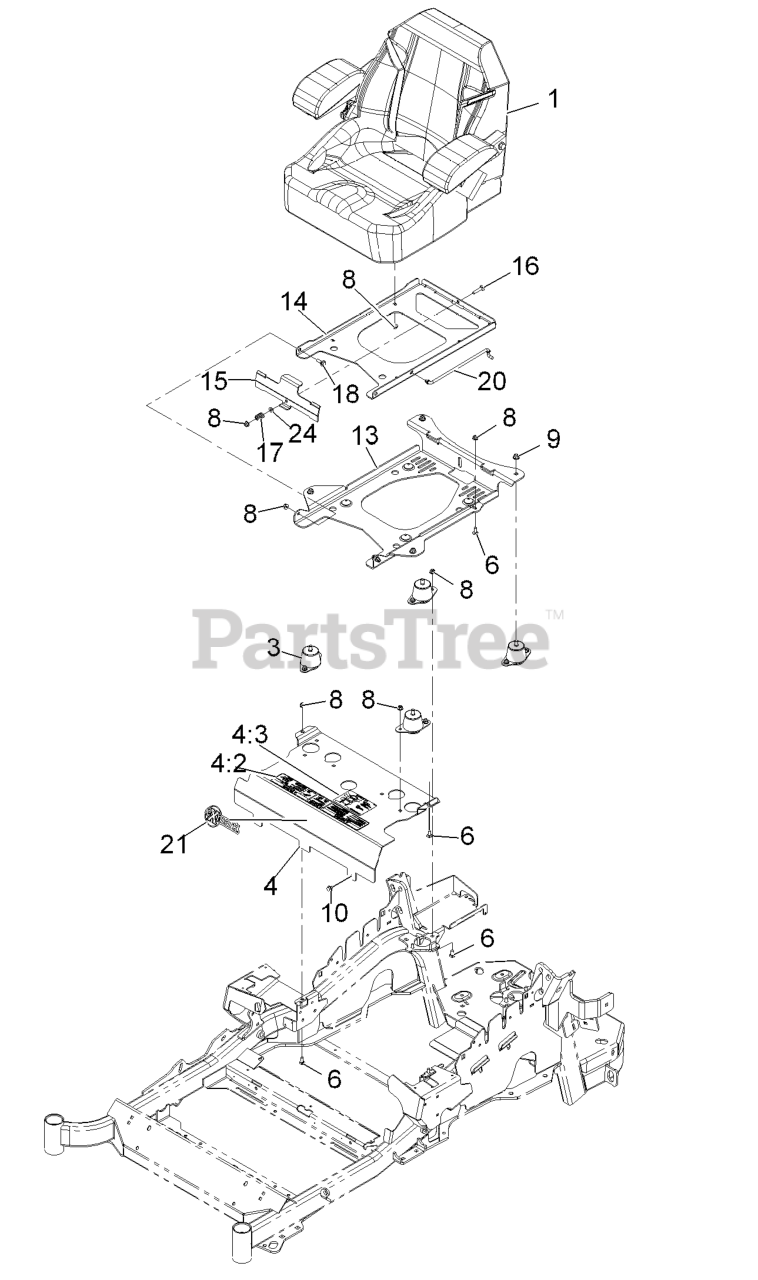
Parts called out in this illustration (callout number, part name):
3	ISOLATOR-SEAT
4	MOUNT-SEAT
4:2	DECAL-CONSOLE
4:3	DECAL-SERVICE AID
6	SCREW-CARR
8	NUT-HF, NI
9	NUT-HF, NI
13	PLATE-SUPPORT, SEAT TILT
14	PLATE-FRAME, SEAT TILT
15	PLATE-LATCH, SEAT
16	BOLT-CARR
17	SPRING-COMPRESSION
18	SCREW-SHOULDER
20	ROD-PROP
24	WASHER-PLAIN
